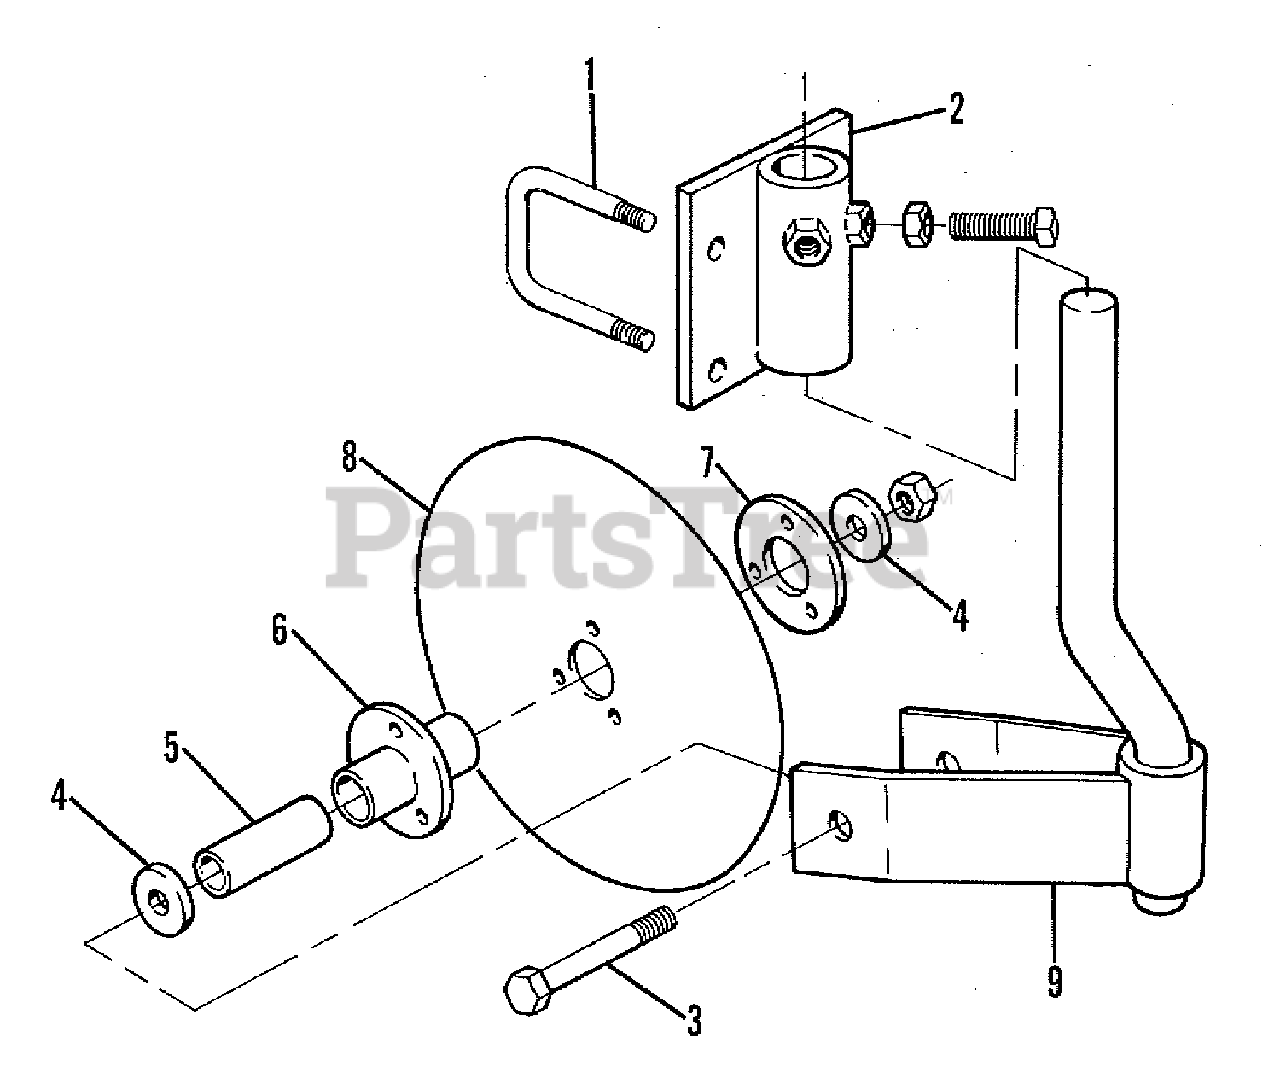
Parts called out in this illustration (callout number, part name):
1	LOCKWASHER, 1/2
2	CLAMP ASSEMBLY
2	SETSCREW, Square Head, Cup Point, 5/8NC x 1-1/4
4	WASHER, Axle Bolt
7	FLANGE, Hub
9	SHANK & YOKE ASSEMBLY
